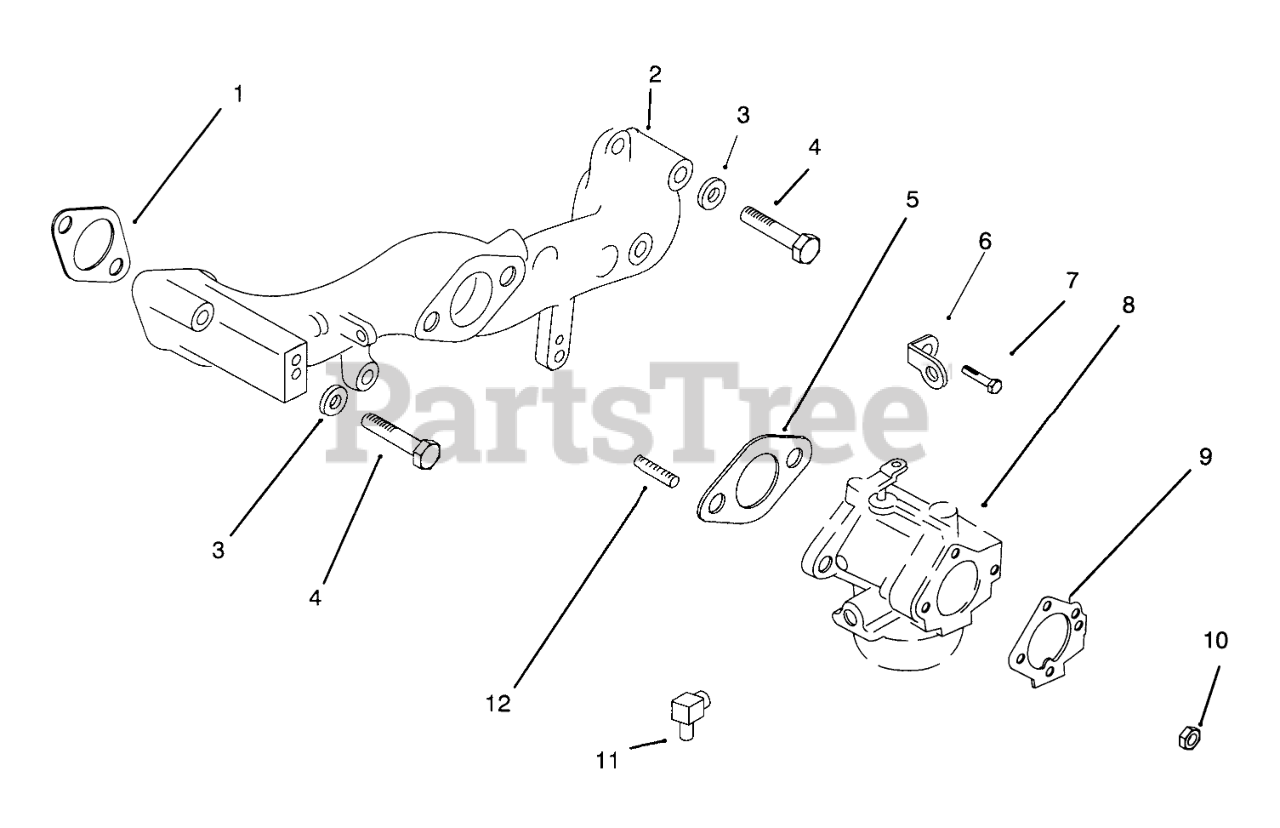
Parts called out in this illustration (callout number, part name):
1	Gasket-Intake Manifold
2	Manifold,Intake
3	Washer
4	Screw
5	Gasket
6	Strap Lifting
7	Screw
8	Carburetor Kit w/Linkage
9	Gasket
10	Nut
11	Connector-Hose
12	Clip
